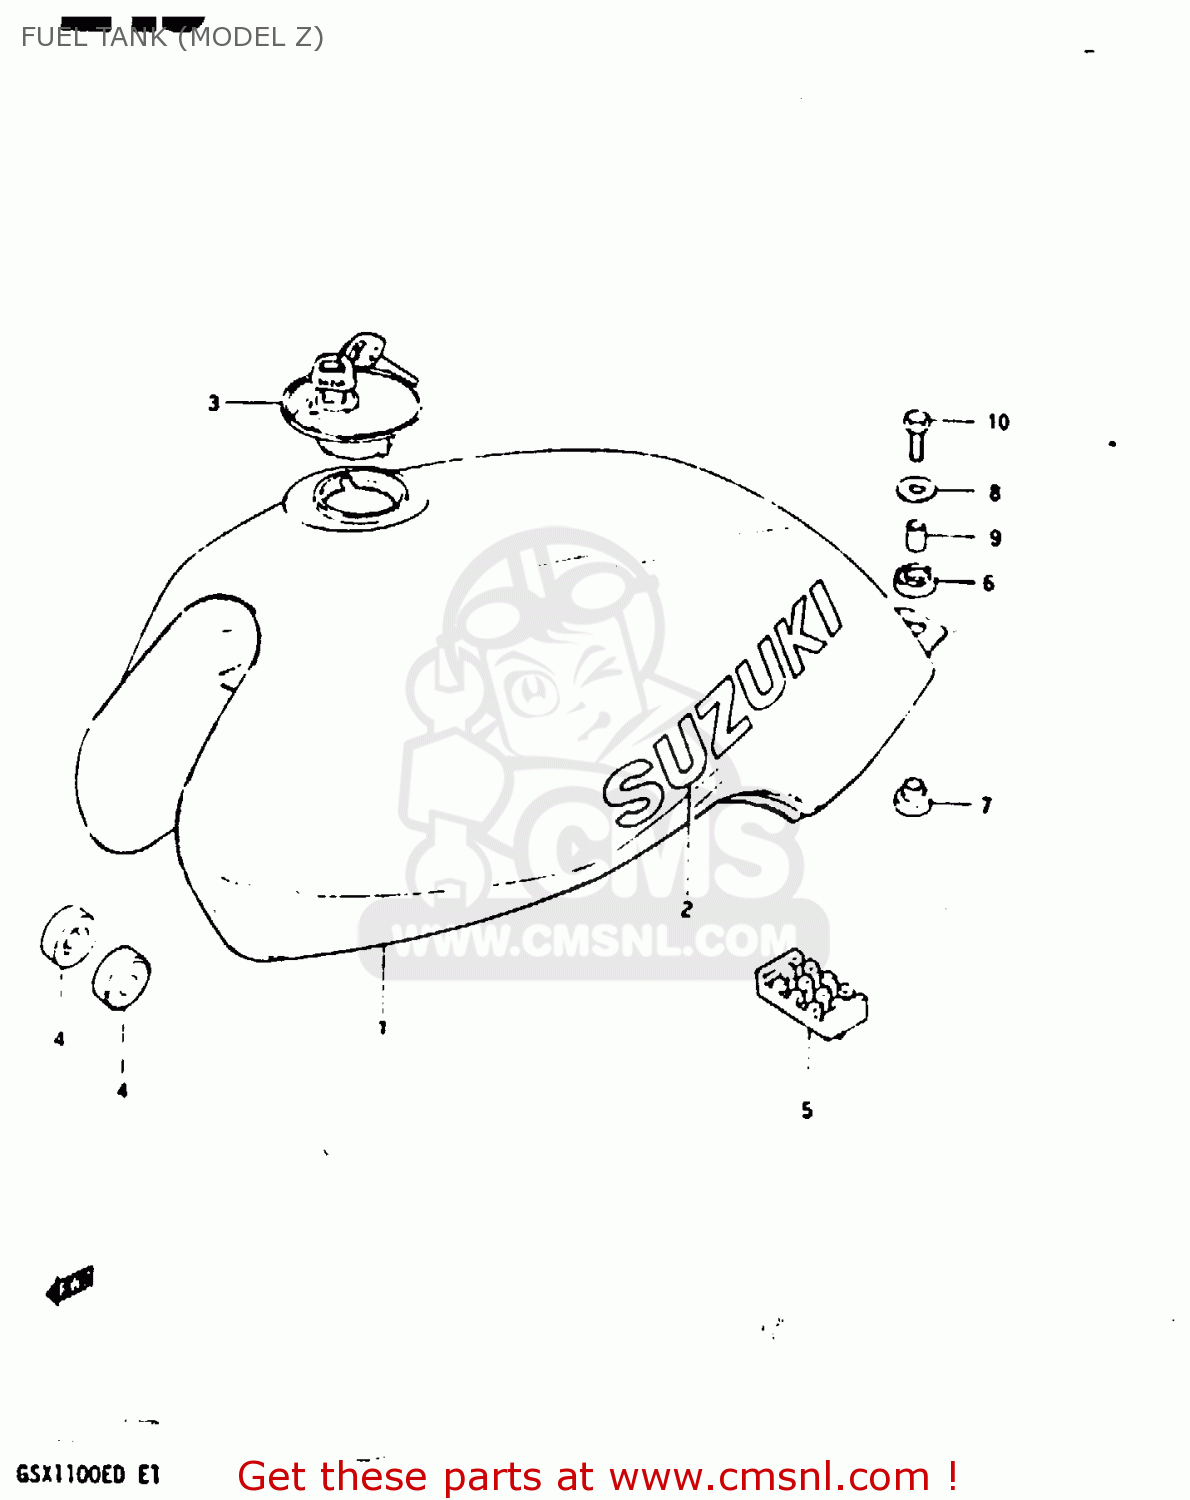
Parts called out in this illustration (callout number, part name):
1	TANK, FUEL (GOLD)
2	EMBLEM(ORANGE)
3	CAP SET,FUEL TANK
4	CUSHION
5	CUSHION,FUEL TANK CTR
6	CUSHION
7	CUSHION
8	WASHER (6.5X24X1.6)
9	SPACER
10	BOLT
